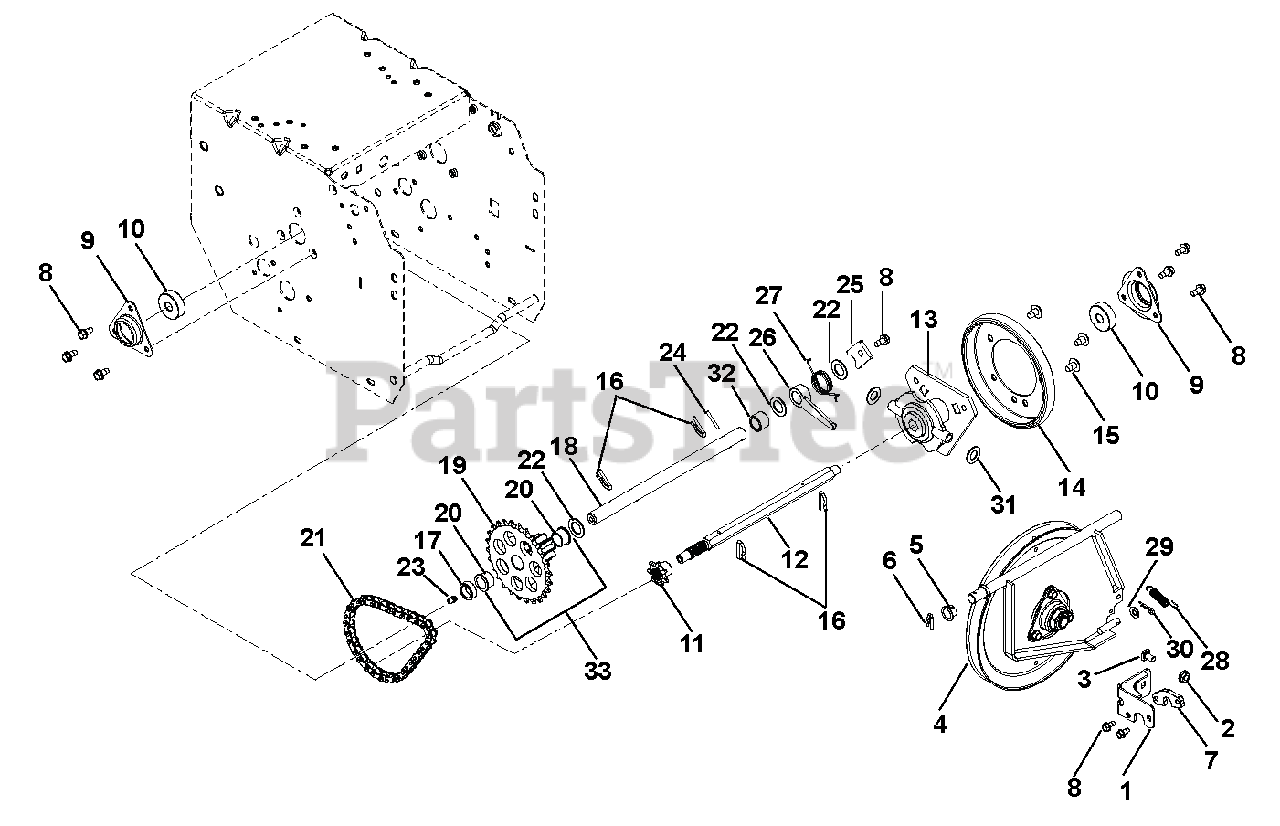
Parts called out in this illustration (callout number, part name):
1	WELDMENT, FRAME BRACKET
2	@NUT-LK-TOP-FLG .31-18 YWZC
3	@BLT-RHDSSQNK .31-18X.62 G5YZ
4	PLATE, SWING - ASSEMBLY
5	BUSHING, POLYLINER-.50 SPLIT
6	CLIP, SPRING
7	SPACER, SWING GATE
8	SCR-TAP .25-20X.50 HWH TR YWZ
9	FLANGE, BEARING
10	BRG-BALL .437X1.375X.437
11	SPROCKET, PINION 7T W/SPLINE
12	SHAFT, HEX W/SPLINE
13	CARRIER, DRIVE DISK
14	FRICTION, DISC
15	SCR-TAP SERRDHDTX .31-18X.50BP
16	PIN, SPRING CLIP
17	BSHG-SLV, .635X.880X.305
18	SHAFT, PINION
19	PINION & SPROCKET
20	BSHG-FLG .625X.750X.500X.875
21	CHAIN - #41, 32 PITCHES
22	WSHR-FL-STL .630X1.005X.062 YZ
23	ZERK,FITTING .25X.125 DRIVE IN
24	@PIN-GRV .125X1.00 TP E ALLOY
25	TAB, ANTI ROTATION
26	LEVER, LOCK ARM
27	SPRING, TORSION
28	SPRING, EXT. .043X.438X1.64
29	@WSHR-FL-STL.344X.688X.065YWZC
30	PIN-HAIR INT .08X.18X1.18 YWZC
31	WSHR-FL-STL .505X1.00X.062YWZC
32	SPACER, .635X.880X.611
33	PINION & SPROCKET W/BUSHINGS
